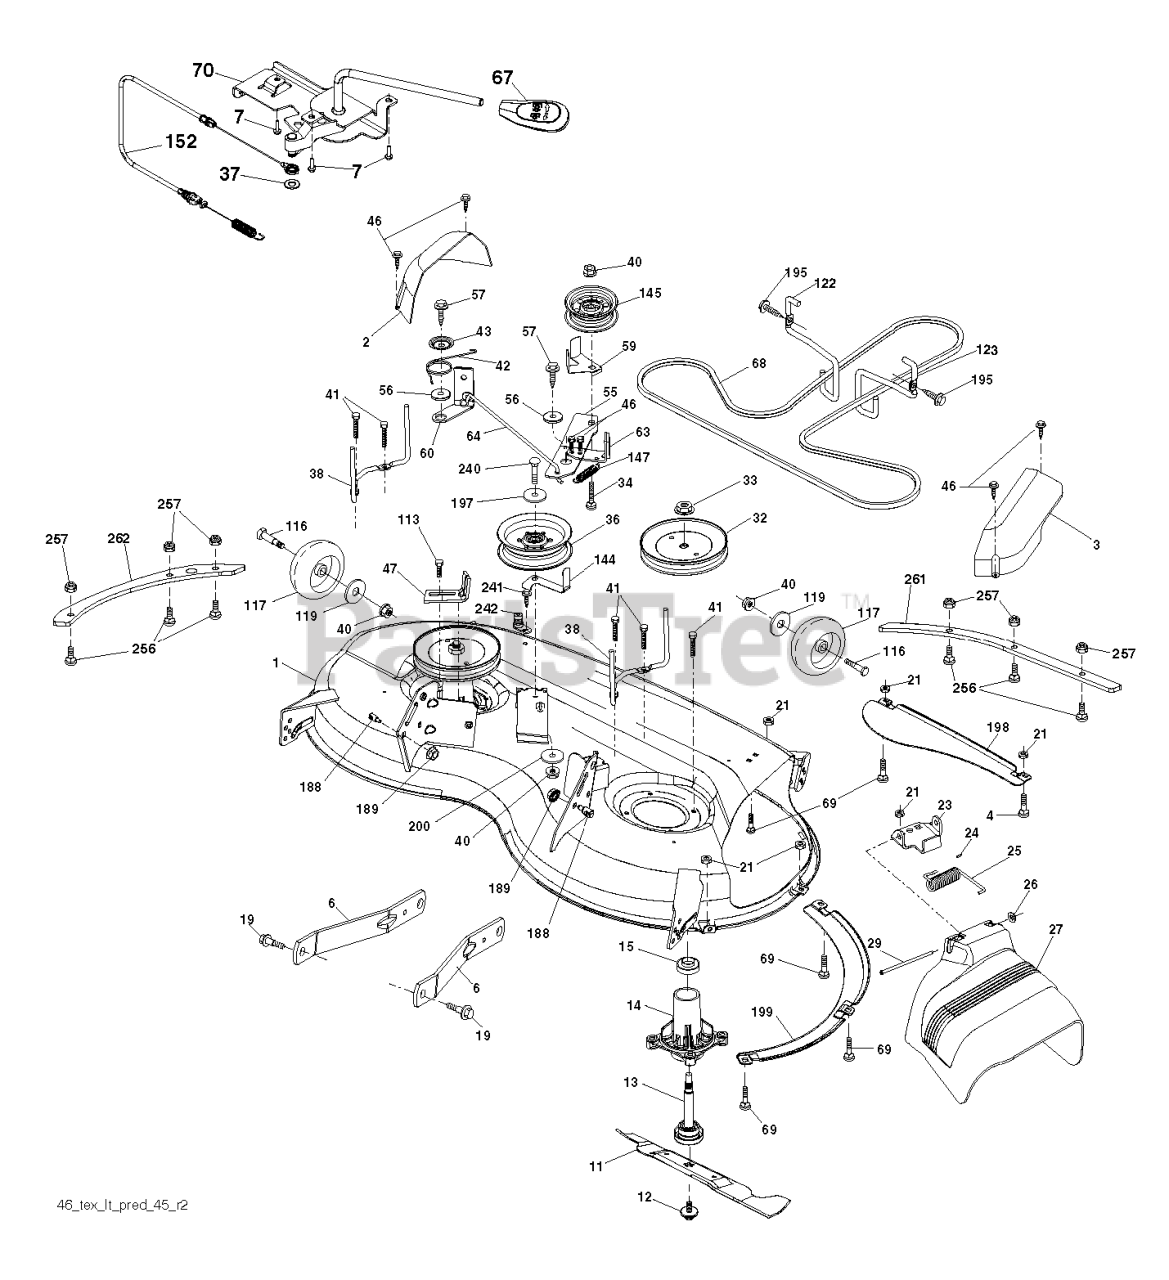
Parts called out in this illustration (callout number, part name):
1	DECK KIT.SVC.WELDMNT.46"405
2	COVER.MANDREL.LH.46"
3	COVER.MANDREL.RH.46"
4	BOLT
6	ARM.SUSPENSION.MOWER.R
7	SCREW.#10 X 0.750.BOS
11	BLADE.MOWER.46".HI.LIFT
12	SCREW.SEMS.7/16-20X1.HEX.HEAD
13	SHAFT ASM.MNDRL.N/GREASEABLE
14	RP.HOUSING.MANDREL.4PT.
15	BEARING.MANDREL.TOP.EXTENDED
19	BOLT.SHOULDER
21	LOCKNUT
23	BRKT.DEFLECTOR.38"2005+
24	CAP-SLEEVE LT
25	SPRING.TORSION.DEFLECT
26	NUT PUSH M
27	SHIELD.DEFLECTOR.MOWER.46"BLAC
29	ROD.HINGE
32	PULLEY.MANDREL.5.438.PD
33	NUT.FLANGE.LOCK.TOP
34	BOLT.3/8-16X1.50
36	PULLEY.IDLER.2006
37	WASHER
38	KEEPER.BELT.MANDREL.PULLEY
40	NUT LOCK FLG 3/8-16 UNC
41	BOLT.HEX.WASHR.HED.313-18X1.19
42	SPRING.TORSION.BRAKE
43	SRPING.TORSION.RETAINE
46	SCREW.1/4-20X5/8
47	BRKT.CLUTCH.CABLE
56	SPACER.RETAINER
57	SCREW 3/8-16X1
59	GUARD, BELT
60	ARM BRAKE MOWER RH 38"
63	ARM BRAKE MOWER
64	LINKAGE BRAKE
67	HANDLE.CLUTCH.CABLE.LT
68	V-BELT
69	BOLT
70	CLUTCH.ASM.MANUAL.YT.PREDATORQ
113	BOLT.5/16HEX.WHS.HD
116	BOLT.SHOULDER.3/8-16X3-5/8.
117	WHEEL.GAUGE.RALLY
119	WASHER
122	KEEPER BELT ENGINE LH
123	KEEPER BELT RH
144	KEEPER.BELT.MOWER
145	PULLEY.IDLER.48"PRIMARY
147	SPRING RETURN
152	CABLE.MECHANICAL.CLUTCH
188	STUD.FASTNER.W/ANTI-ROTATE
189	NUT LOCK HEX FLANGE 5/16-18
195	SCREW, 3/8-16X3/4
197	WASHER
198	BAFFLE CENTER FRONT
199	BAFFLE FRONT RH
200	WASHER.13/32 X 1 X 1/2.11GUARD
240	BOLT-HEX EAK
241	SCREW.TT.#10-32X.5.3/8.FLANGE
242	PORT.WASHOUT
256	RHSNB, 1/4-20 X 1, GR5
257	NUT T
261	PLATE.REINF.DECK.46".FRONT.BLK
262	PLATE.REINF.DECK.46".SIDE.BLK
